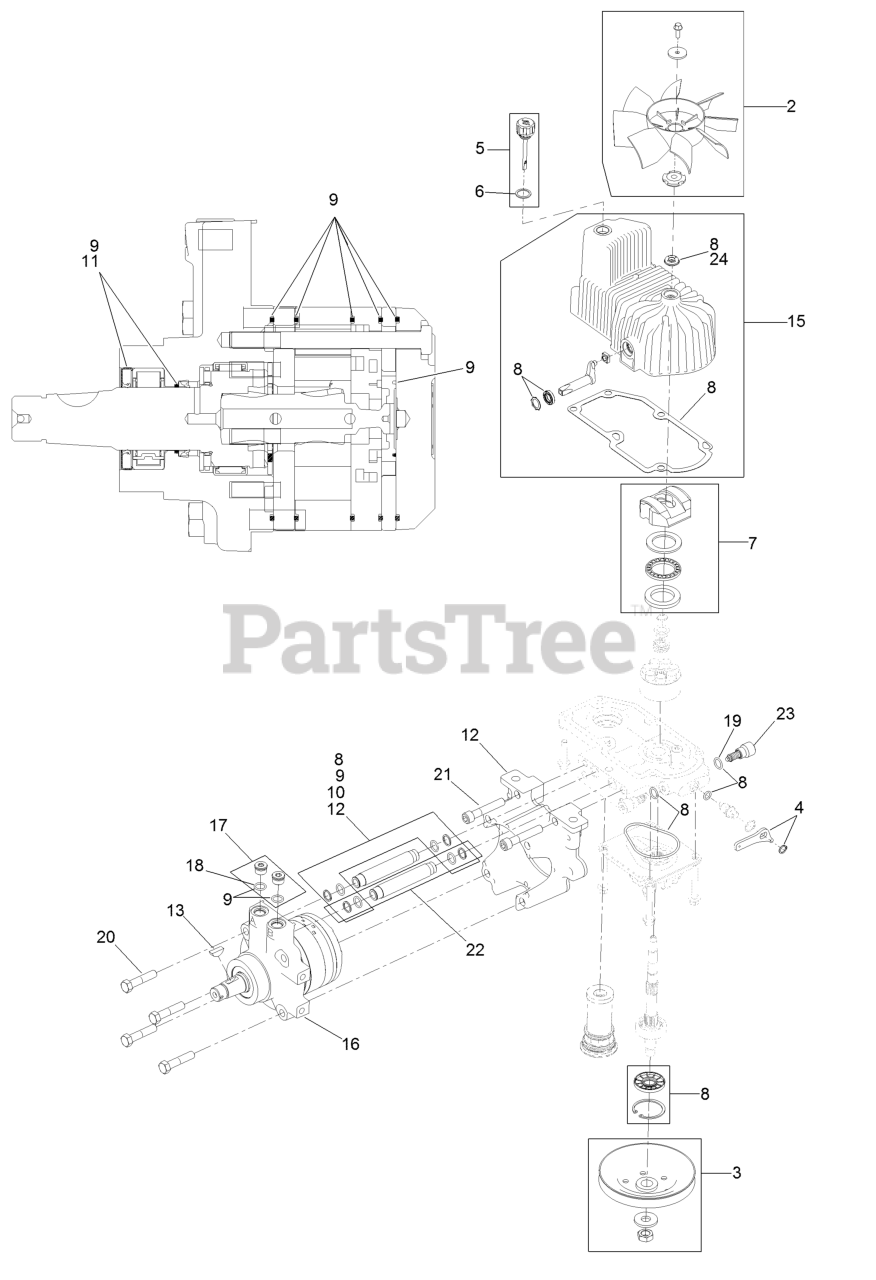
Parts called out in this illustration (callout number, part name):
2	Fan Kit
3	Pulley Kit
4	Handle-Bypass Valve, Hydro
5	Dipstick-Hydro W/Gasket
6	Gasket-Dipstick, Hydro
7	Swash Block Kit
8	Pump Seal Kit
9	Motor Seal Kit
10	Tube Seal Kit
11	Output Shaft Seal Kit
12	Nose Cup-Uht
13	Key-Woodruff
15	Housing-LH
16	Motor-Hydraulic, LH 280Cc
17	Magnetic Plugs Service Kit
19	O-Ring-Check Valve
20	Screw HH
21	Screw-HSH
22	Hydraulic Tube Kit
23	Shock Valve, 16Cc Hydro
24	Seal-Fan Drive
99	Flow Test Kit
